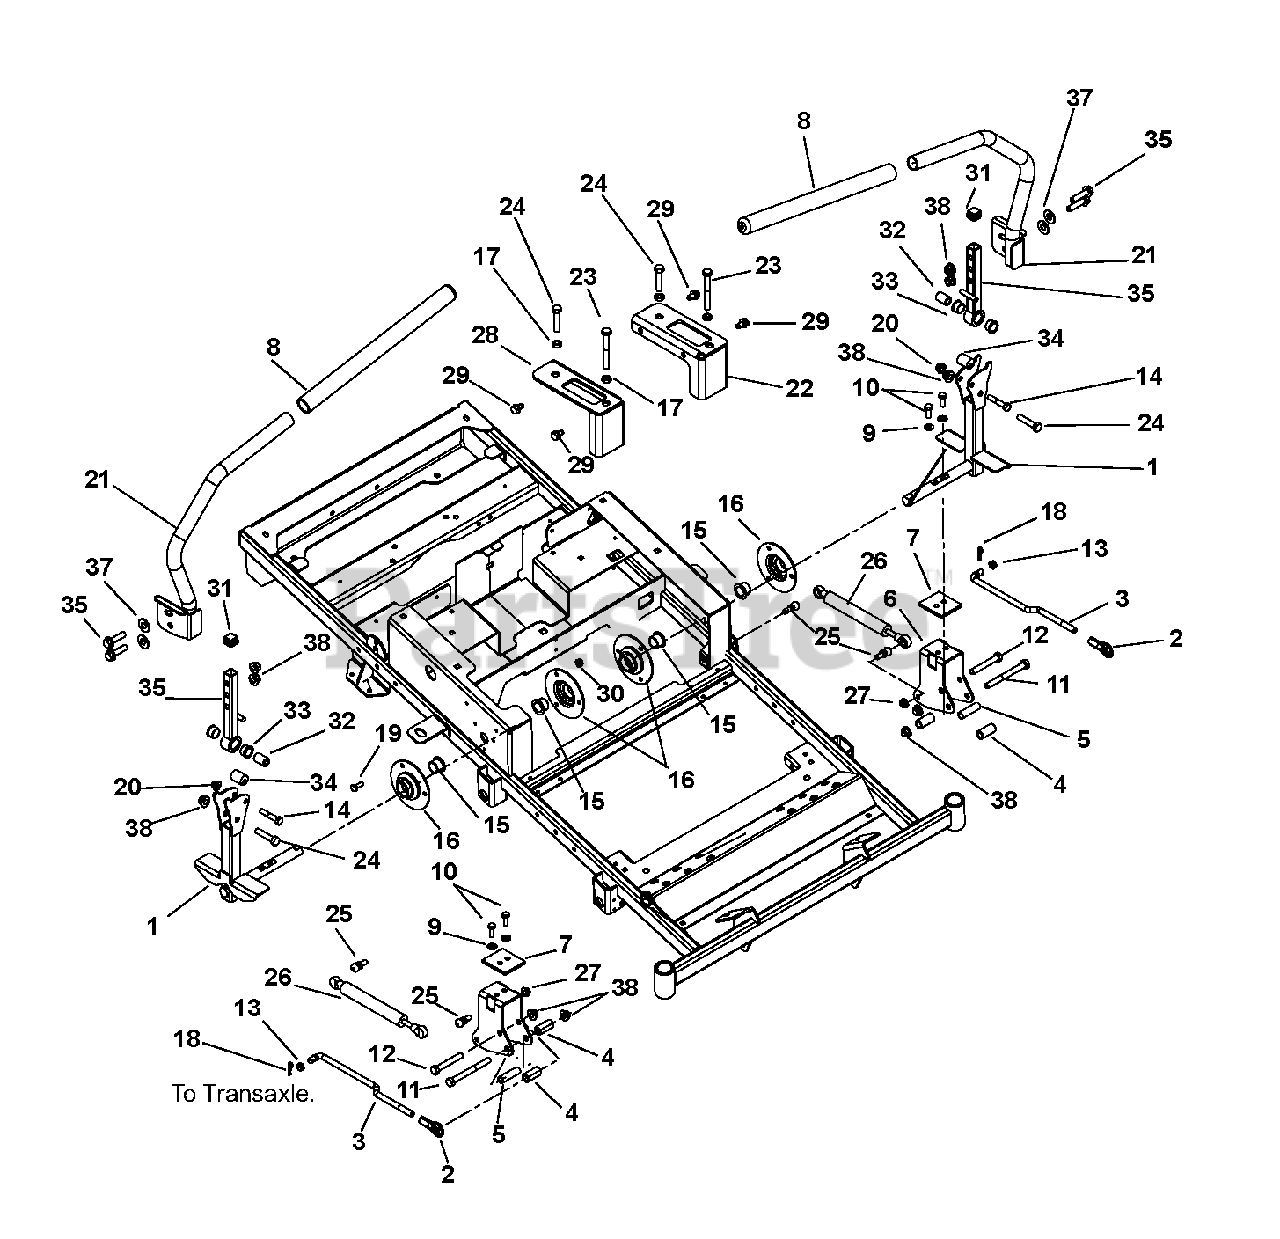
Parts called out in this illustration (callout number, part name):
1	Weldment, Control Arm
2	Rod End, .38 Right Hand
3	Link, Transmission
4	Bushing, Spacer .390 x .625 x 1.25 Promaster
5	Spacer, Steering
6	Bracket, Steering
7	Plate, Steering Reinforcing
8	Grip, Handlebar 15" Foam
9	Washer, Locking .31 x .078
10	Bolt, Hex .31-18 x 1.00 Grade 8
11	Bolt, Hex .38-16 x 3.75 Grade 5
12	Bolt, Hex .38-16 x 2.50 Grade 5
13	Bushing, Polyliner 322-C
14	Bolt, Hex .31-18 x 1.75 Grade 5
15	Bushing, Flange .750 x 1.000 x .625 x 1.250
16	Bearing Flange
17	Nut, Hex Jam .375-16
18	Pin, Hair Internal .08 x .18 x 1.18
19	Bolt, Hex .25-20 x .75 Grade 5
20	Nut, .31-18 Nyloc Flange
21	Weldment, Steering Handle Right Hand
22	Bracket, Left Hand Speed Control
23	Bolt, Hex .38-16 x 3.00 Grade 5
24	Bolt, Hex .375-16 x 1.750 Full Thread
25	Stud, Ball
26	Damper, Control
27	Nut, Locking Top Flange .31-18
28	Bracket, Right Hand Speed Control
29	Screw, Tapping .31-18 x .50 Hex Washer Head
30	Nut, Locking Top Flange .25-20
31	Cap Plug, Square .75-14-20 Ribbed
32	Spacer, .375 x .625 x .970 (PM)
33	Bushing, Flange, .625 x .750 x .450 x .875
34	Bushing, Eccentric .31 x .75 x .97
35	Weldment, Upper Control Arm
36	Bolt, Serrated Hex Flange Washer Head .375-16 x 1.25
37	Washer, Flat Steel .406 x .812 x .065
38	Nut, Locking Center Jam .375-16
